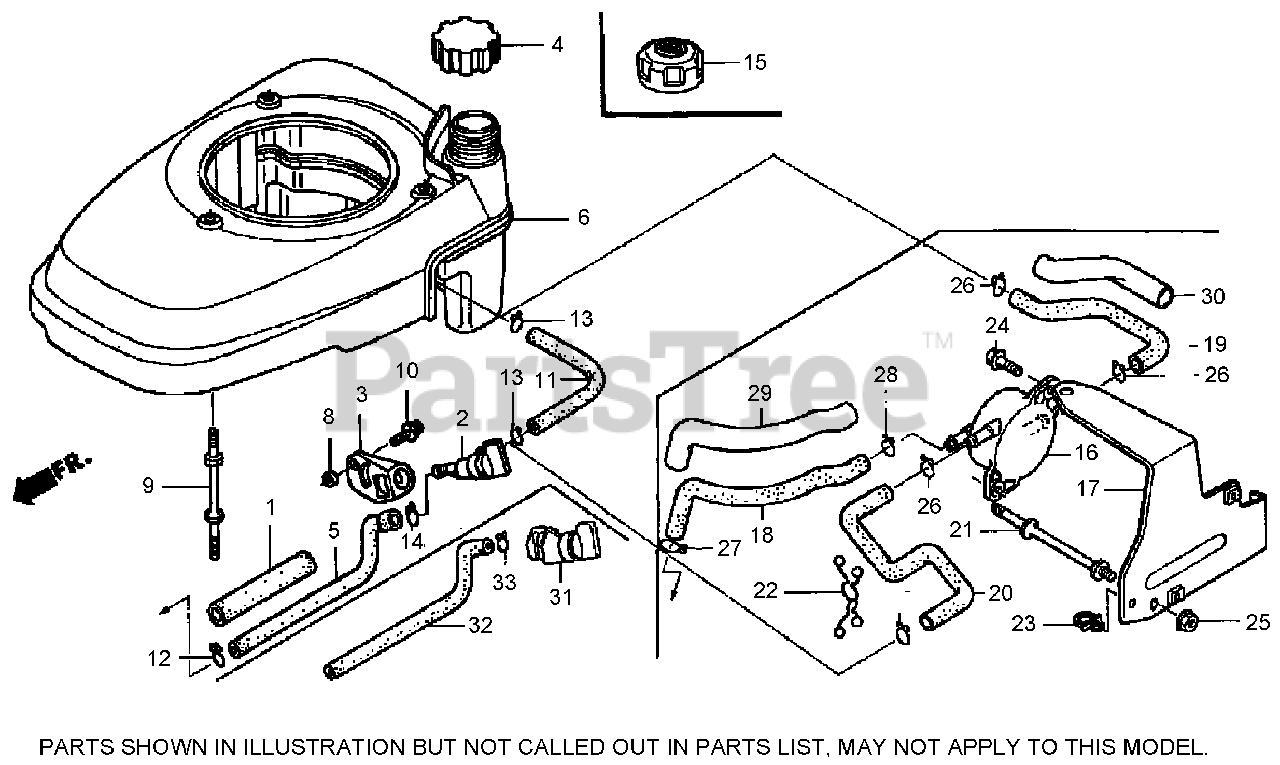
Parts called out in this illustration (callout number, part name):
1	RUBBER-SUPPORTER (107MM)
2	PETCOCK ASM.
3	BRACKET, PETCOCK
4	CAP ASM., FUEL TANK
5	TUBE, FUEL
6	COVER, FAN NH1 (BLACK)
8	COLLAR, FUEL PETCOCK
9	BOLT, STUD
10	SCREW-WASHER (5X10)
11	TUBE, FUEL TANK
12	CLIP-TUBE (B8)
13	CLIP-TUBE (B10)
14	CLIP-TUBE (C9)
